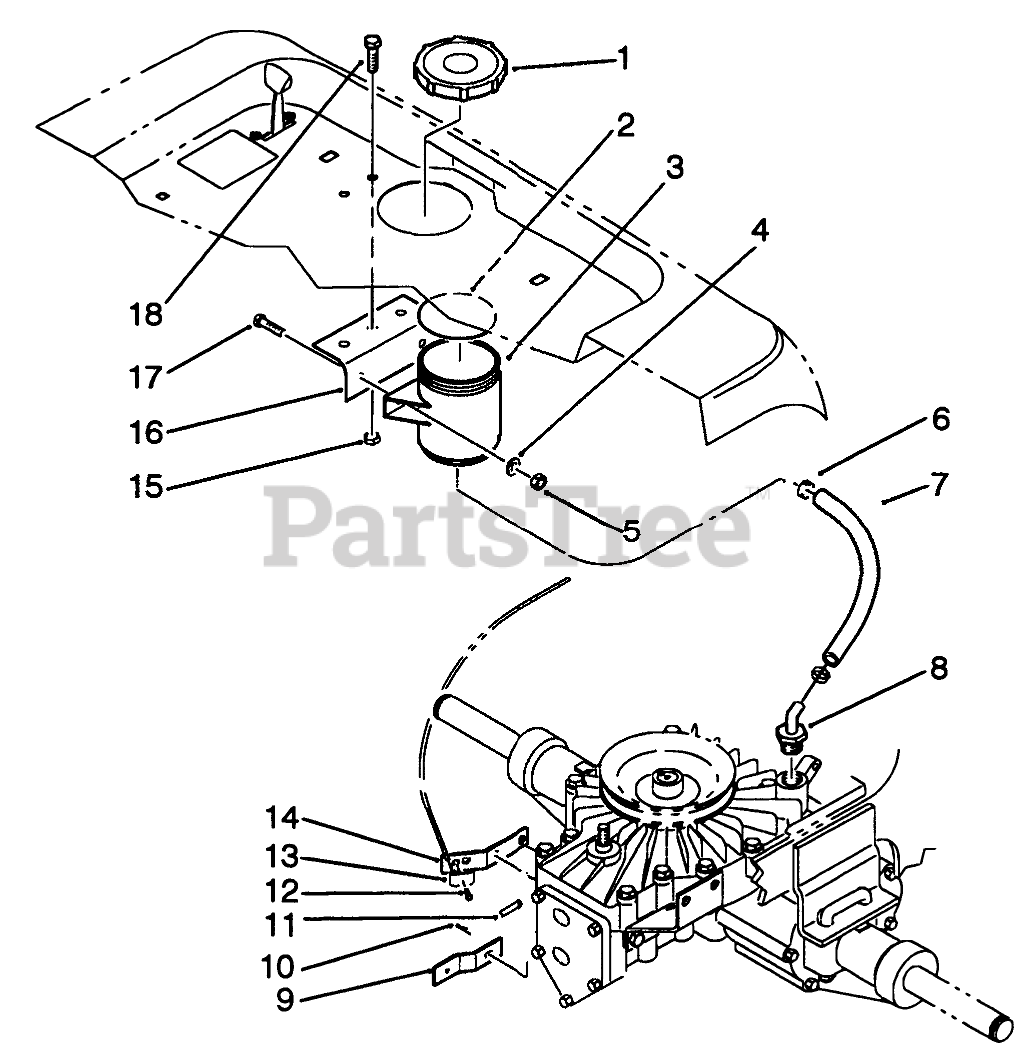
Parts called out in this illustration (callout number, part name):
1	ASS'Y-RESERVOIR
2	COVER GASKET
3	RESERVOIR
4	WASHER-FLAT
5	NUT-LOCK, NI
6	CLAMP .875
7	HOSE-7"
8	HOSE BARB
9	Plate
10	Cotter Pin
12	Screw
13	CLAMP THROTTLE
14	PLATE-MTG
15	NUT-LOCK, NI
16	BRACKET R
17	Bolt
18	SCREW-HH
